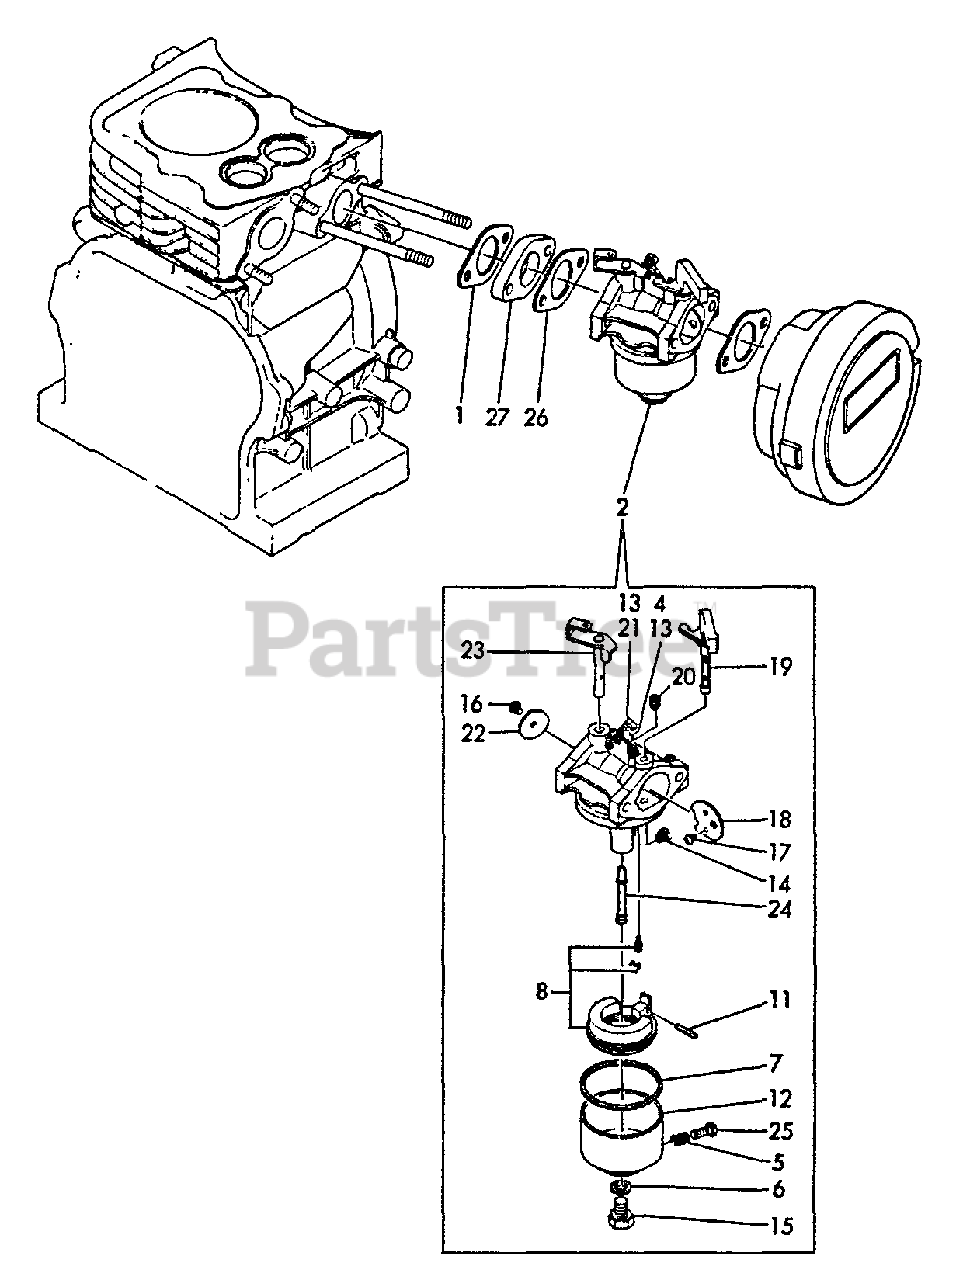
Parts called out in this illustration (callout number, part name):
1	GASKET, EXHAUST
2	CARBURETOR
4	SCREW
6	GASKET
7	GASKET
8	NEEDLE ASSY (SUS)
11	PIN
12	BODY, FLOAT CHAMBER
14	JET, MAIN
15	BOLT
16	SCREW
17	SCREW
18	VALVE, CHOKE
19	SHAFT, CHOKE
20	JET, PILOT
21	SCREW
22	VALVE, THROTTLE
23	SHAFT ASSY, THROTTLE
24	NOZZLE, MAIN
25	SCREW
26	GASKET, INTAKE
27	SPACER
